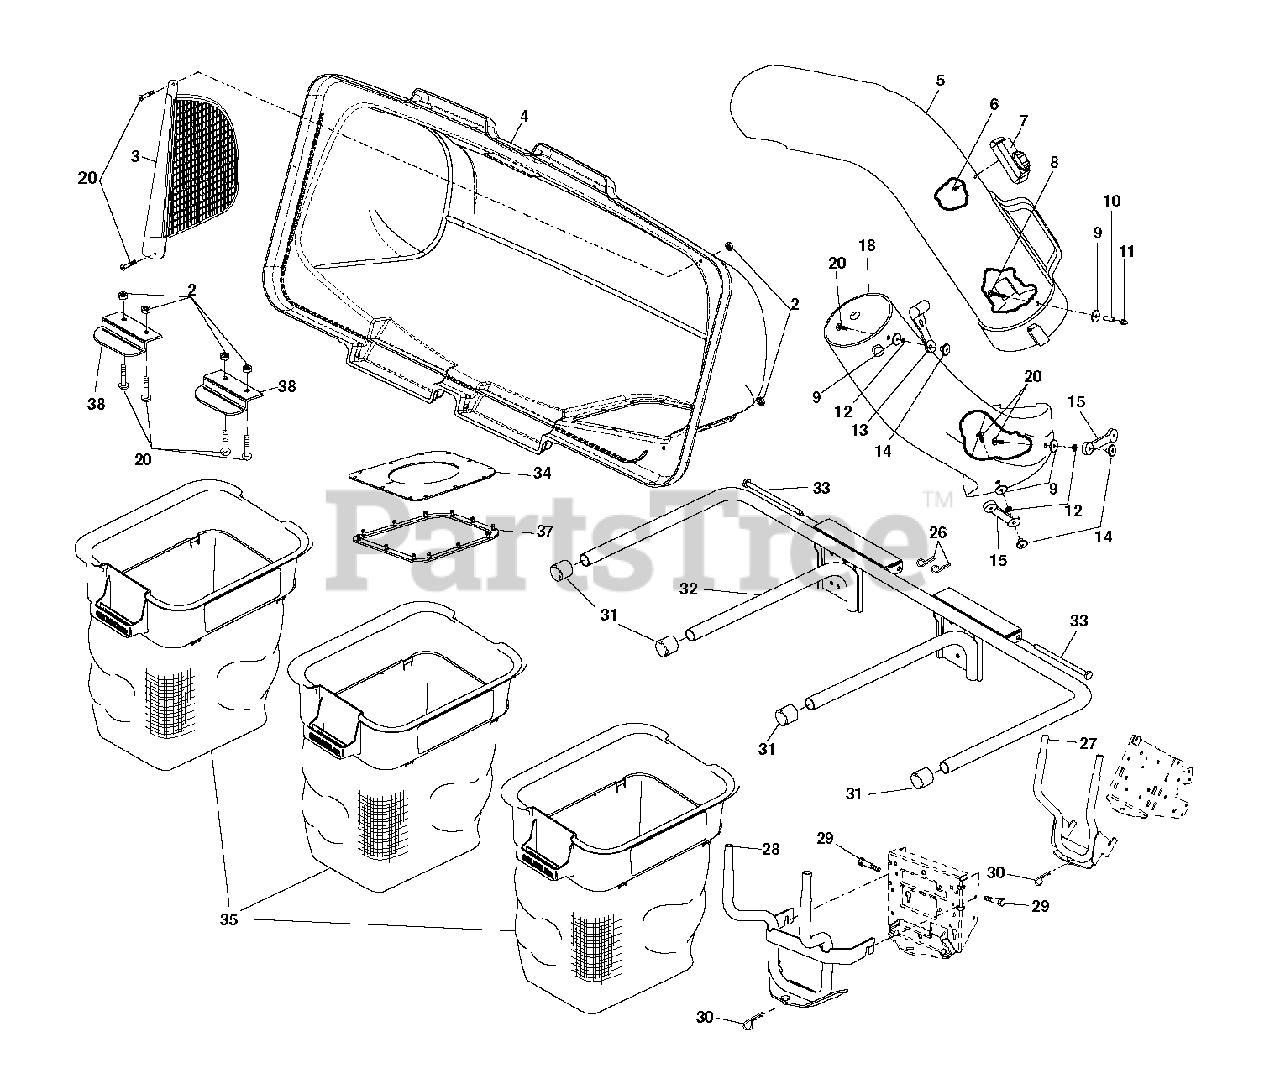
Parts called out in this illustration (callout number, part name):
3	SCREEN.COVER.BAGGER
4	COVER.ASM.3BIN.GENERIC.
5	UPPER CHUTE 54"
7	INDICATOR ASM BAG
8	SCREW
9	RP STEEL WASHER
11	NUT
12	LOCKWASHER (3 2)
13	LATCH.HOOD.
14	WELDNUT
15	LATCH ASSY
18	CHUTE.BAGGER.LOWER.54"
20	SCREW
26	Retainer Spring
27	BAGGER.ASM.SUPPORT.GT.TEX.BLAC
28	BAGGER.ASM.PNT.3-BIN.
29	SHOULDER BOLT, SELF-TAP
30	SPRING.RETAINER.YELLOW.ZINC
31	PLUG, TUBING END
32	BAGGER.ASM.FRAME.3BIN.BLACK
33	BAGGER.HINGE.PIN
34	SEAL.BAGGER.TOP.3-BIN.BLK
35	CONTAINER BAG, SOFT
37	GASKET.COVER.BAGGER
38	LATCH CER38
